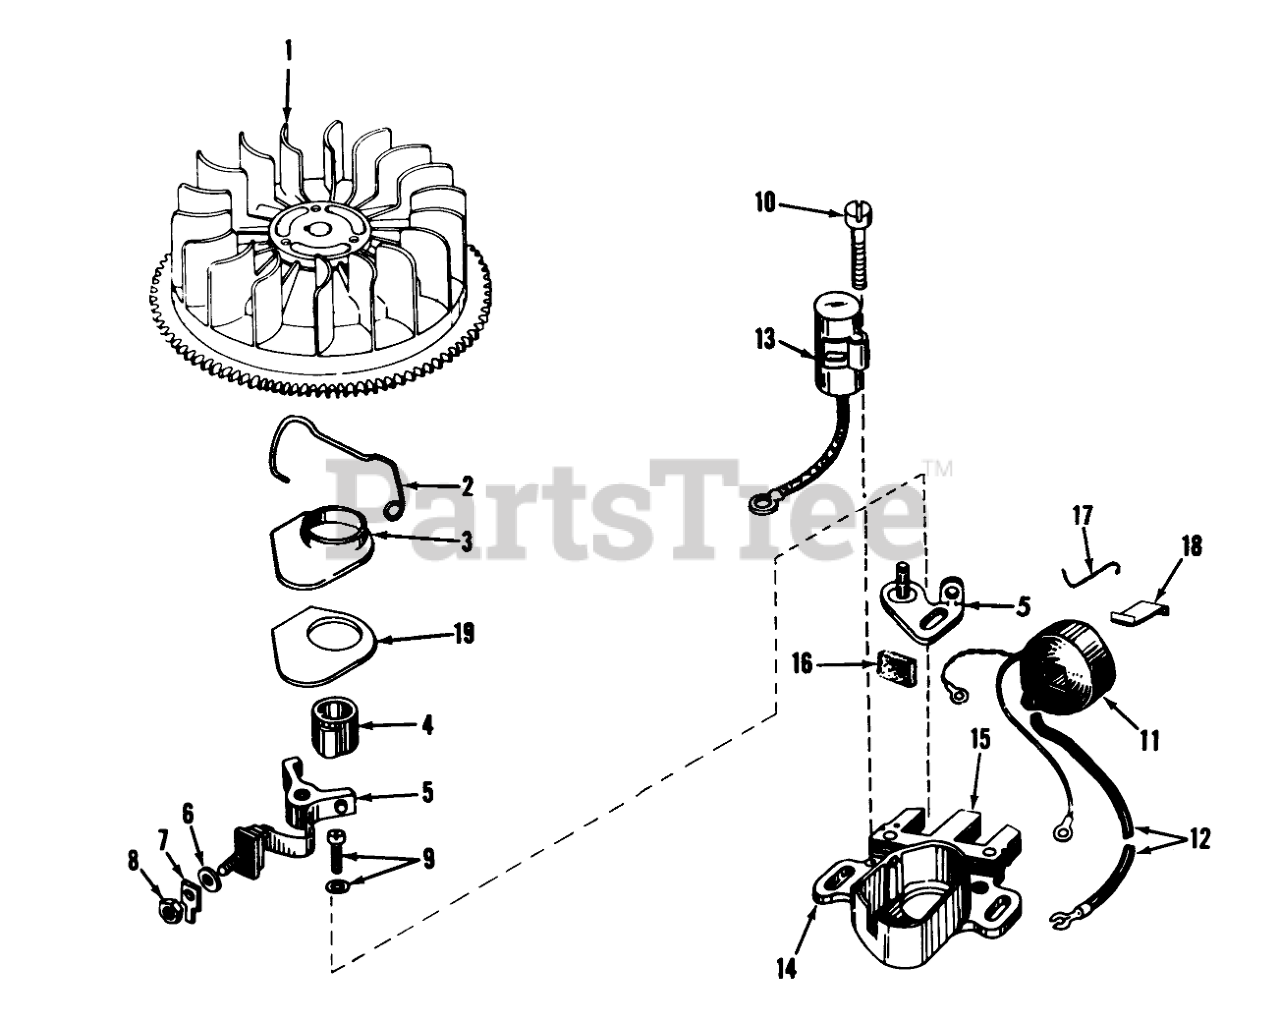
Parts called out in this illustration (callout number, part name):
1	Flywheel
2	Spring Breaker Box
3	Cover, Dust
4	Cam-Breaker
5	Breaker Assy.
7	Terminal, Ground
9	Breaker Screw
10	Condenser Screw
11	Coil Assy. (Incl. No. 12)
12	Wire, Lead
13	Condenser
14	Core & Plate
15	Stator Assy. (Incl. Nos. 2, 3, 5, thru 14 & 16 thru 19)
16	Felt,Cam Wiper
17	Clip, Coil
18	Spring Coil Wedge
19	Gasket, Dust Cover
